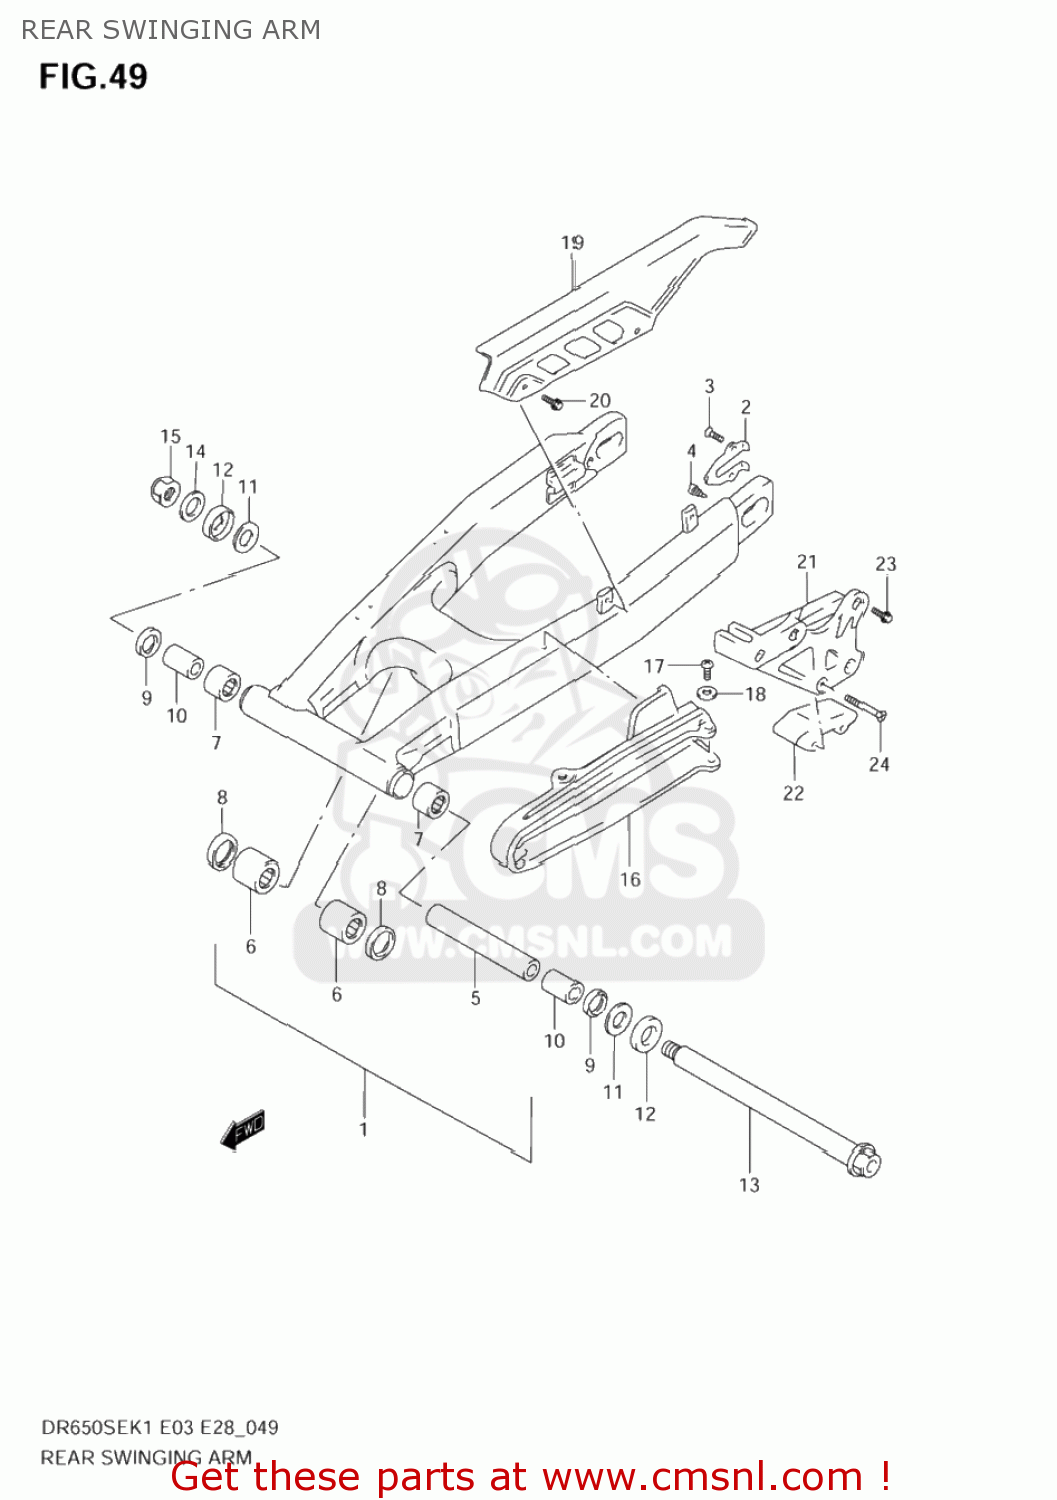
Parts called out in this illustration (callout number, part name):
1	SWING ARM ASSEMBLY,REAR
2	PLATE,RR SWING ARM AXLE
3	SCREW(5X8)
4	STOPPER,CHAIN ADJUSTER
5	SPACER,SWGARM PIVOT CTR
6	BEARING(20X27X23.5)
7	BEARING(22X29X30)
8	SEAL,OIL(20X27X5)
9	SEAL,OIL(22X29X4)
10	SPACER,SWGARM PIVOT BRG
11	WASHER
12	COVER,SWINGINGARM PIVOT
13	AXLE,RR
14	WASHER, FIXED DRIVE FACE
15	NUT
16	BUFFER,CHAIN TOUCH DEFENSE
17	SCREW 6X12
18	WASHER
19	CASE,CHAIN
20	BOLT(6X10)
21	GUIDE,CHAIN
22	DEFENSE,CHAIN GUIDE
23	BOLT
24	SCREW
